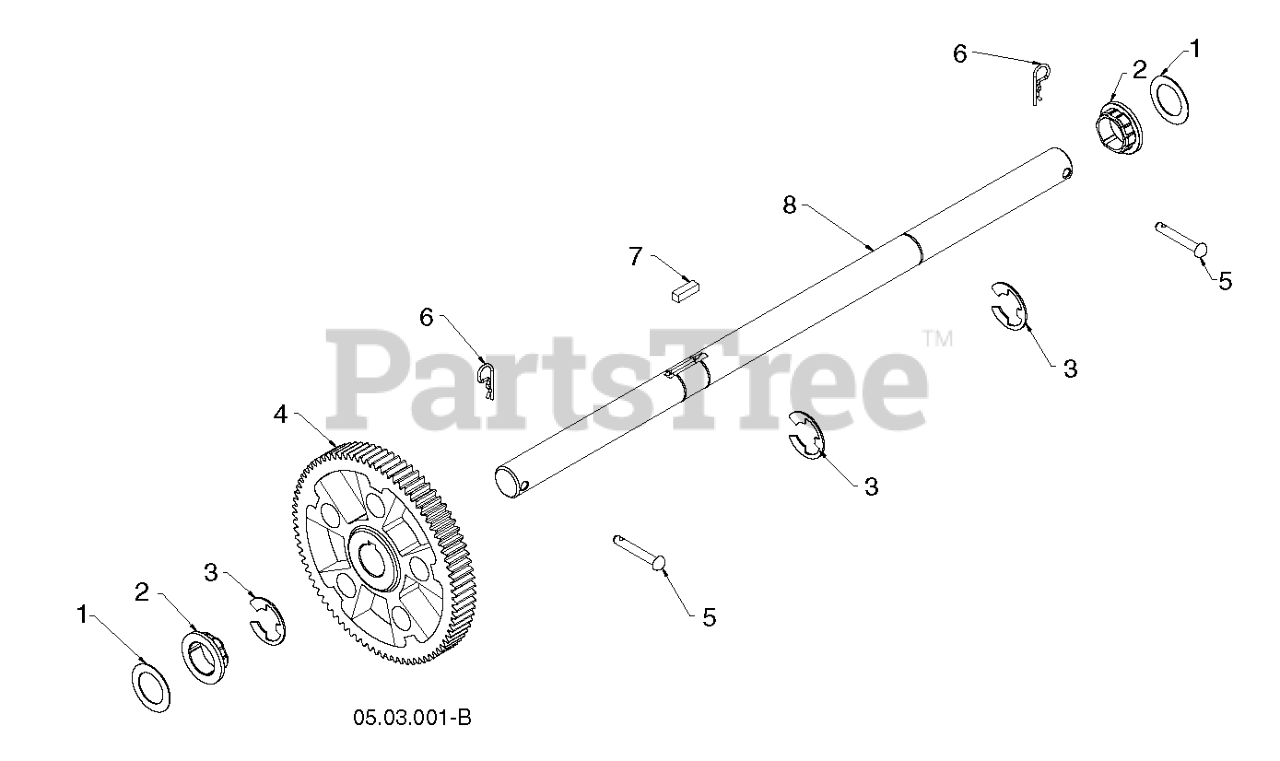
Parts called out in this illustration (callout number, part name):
1	WASHER 1.00
2	BUSHING.HEX.1.SHAFT
3	E-Ring (AYP part number)
4	GEAR.80T.DRIVEN.2PC
5	RIVET
6	Spring Retainer 1" Zinc/cad (AYP part number)
7	KEY, SQUARE 1/4 X .875
8	SHAFT SHAFT,AXLE,
